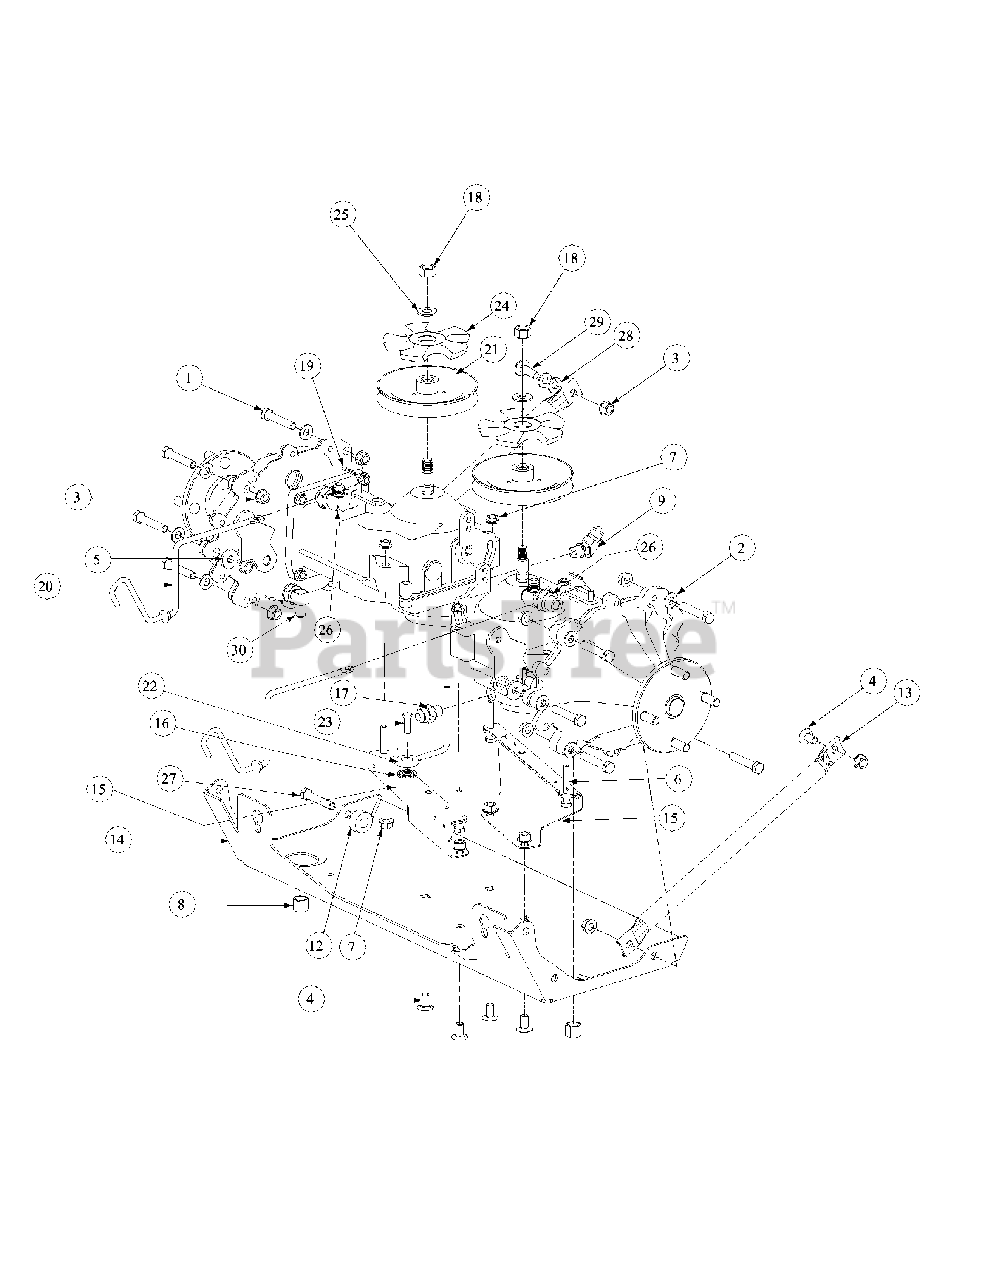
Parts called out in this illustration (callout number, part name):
1	HHCS, 3/8-16, 2.00
2	Flat Washer, 3/8, SAE
3	Hex Nut, 3/8-16, Flange Lock
4	Carriage Bolt, 3/8-16 x .75 Long
5	Flat Washer, .385 x 1.0 OD x .13
6	HHCS, 5/16-18, 2.00
7	Lock Nut, Hex Flange, 5/16-18
8	Nut, Cap, 3/8
9	Elbow Fitting, 3/8-1/2, 45 degree
12	Spacer, .406 ID x 1.00 OD x .38
14	Plate Assembly, Skid
15	Bracket Assembly, Support Pump
16	External Tooth Washer
17	Fitting Connector, 1/2 x 3/8
18	Nut, 1/2-20, Hex Insert Lock Jam
19	Hair Pin, .0721 x 1.12 Long
20	Rod, Release, Pump
21	Pulley, Transmission Hydro, Slotted
22	Guide, Traction Drive Belt
23	Flat Head Screw, 5/16-18 x 1.00
24	Hydro Pulley Fan
25	1/2" Flat Washer
26	Fitting Elbow, 1/2 x 3/8
27	Hex Cap Screw, 3/8-16, 2.50
28	Lock Washer, 3/8
29	Carriage Bolt, 3/8-16 x 1
30	Fitting Elbow, 3/8 x 3/8
